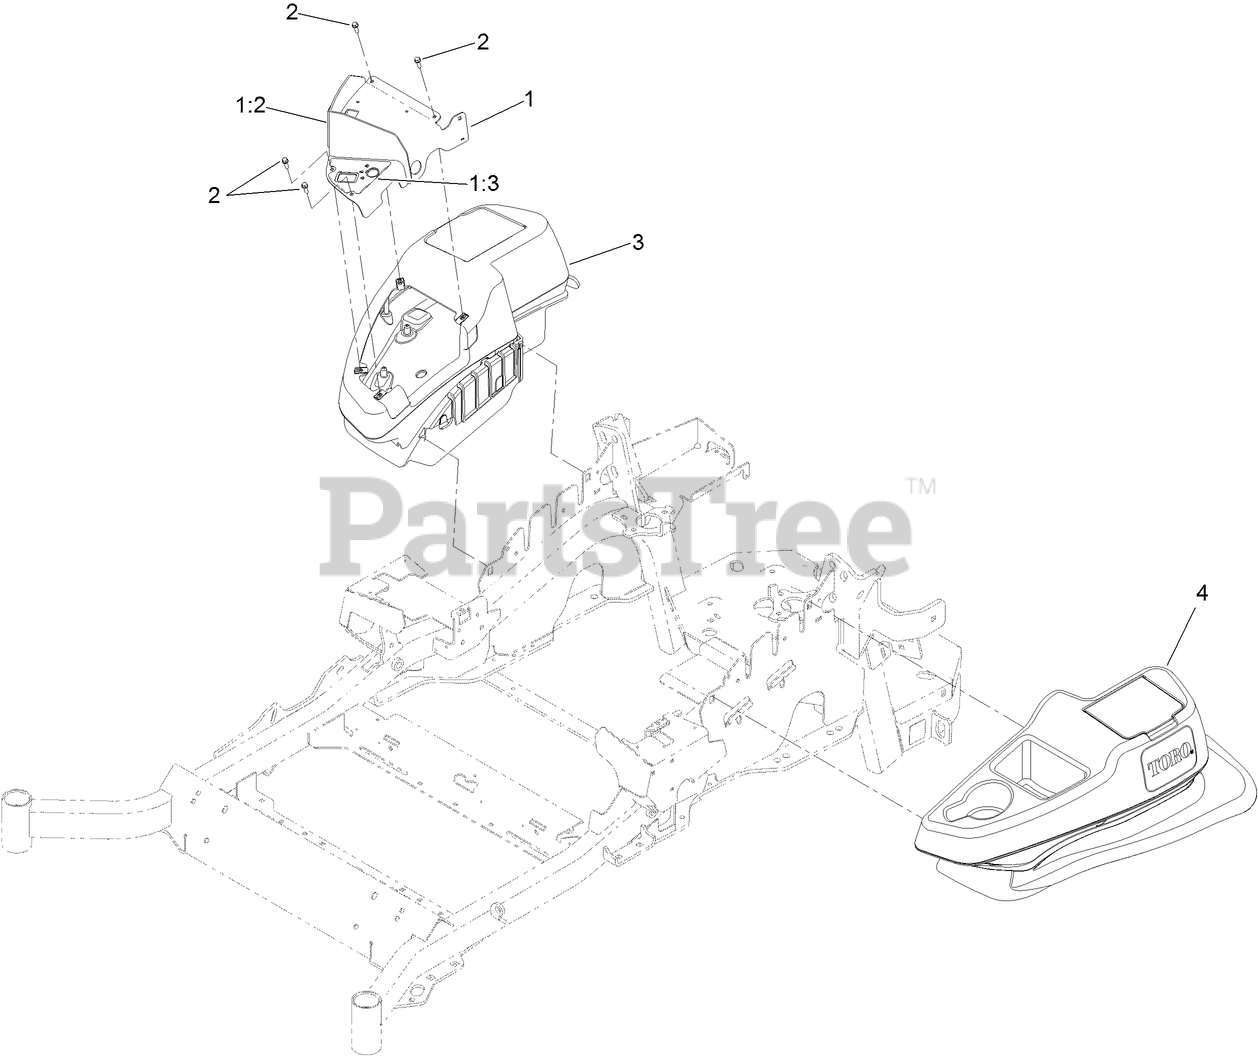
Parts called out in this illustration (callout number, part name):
1	PANEL COVER ASM
1:2	DECAL-HORIZON
1:3	DECAL-CONTROL PANEL
2	SCREW-HWH
3	RH CONSOLE ASM
4	LH CONSOLE ASM
